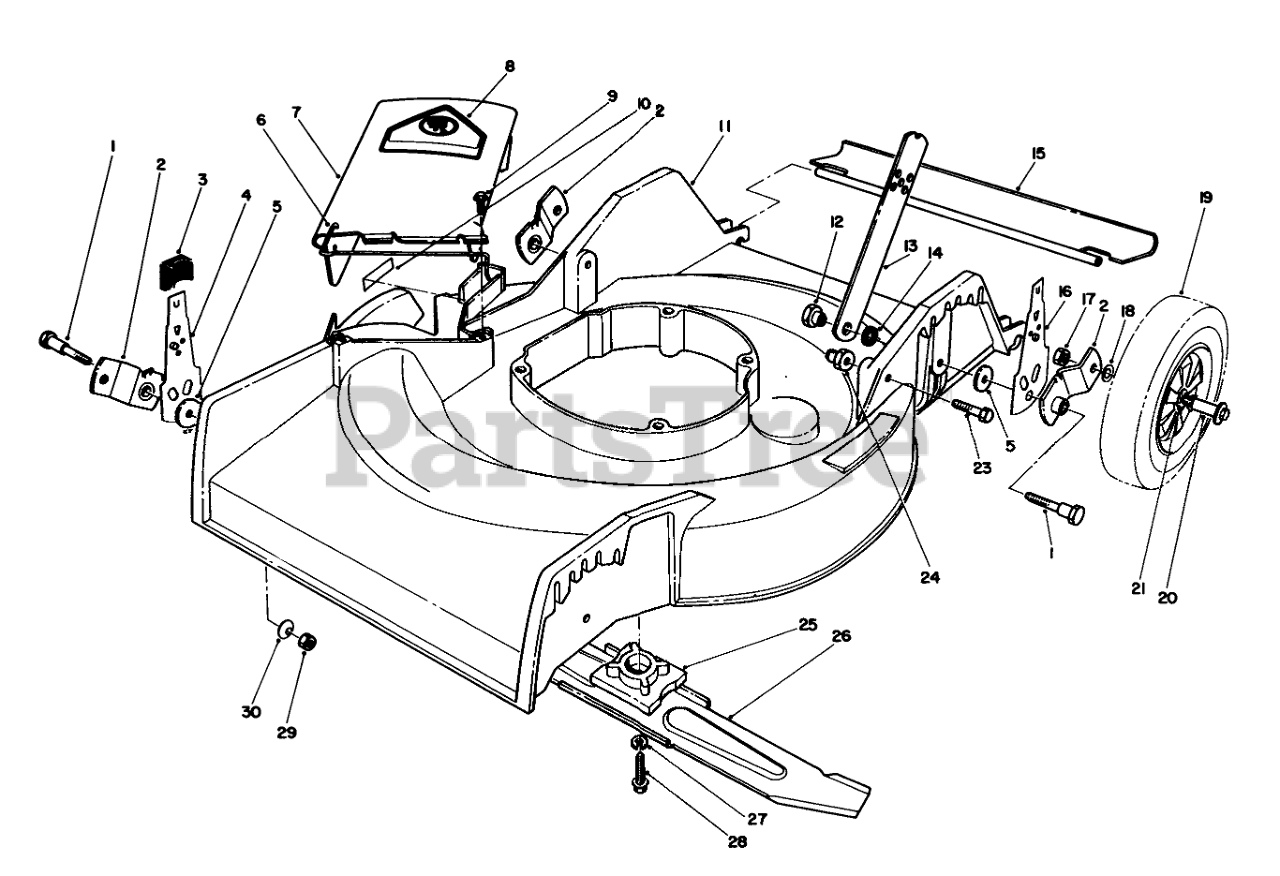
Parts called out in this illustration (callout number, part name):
1	PIVOT SCREW
2	HP PIVOT ARM ASM
3	KNOB-ARM
4	SPRING ARM ASSEMBLY
5	PIVOT WASHER
6	SPRING HINGE
7	Deflector Assembly (Incl. Ref. #6 & 8)
8	DECAL-DANGER
9	SCREW-HWH
10	DANGER DECAL
11	HOUSING W/ DECAL
12	HANDLE PIVOT NUT
13	HANDLE LATCH
14	SPACER
15	SHIELD - TRAILING
16	SPRING ARM ASSEMBLY
17	Nut
18	WASHER
19	Wheel & Tire Assembly (Incl. Ref. #21)
20	BOLT-WHEEL
21	BUSHING
23	SCREW-HH
24	HANDLE PIVOT NUT
25	BLADE RETAINER
26	Blade
27	WASHER-LOCK
28	SCREW-HH
29	NUT-LOCK, NI
30	WASHER-BELLEVILLE
